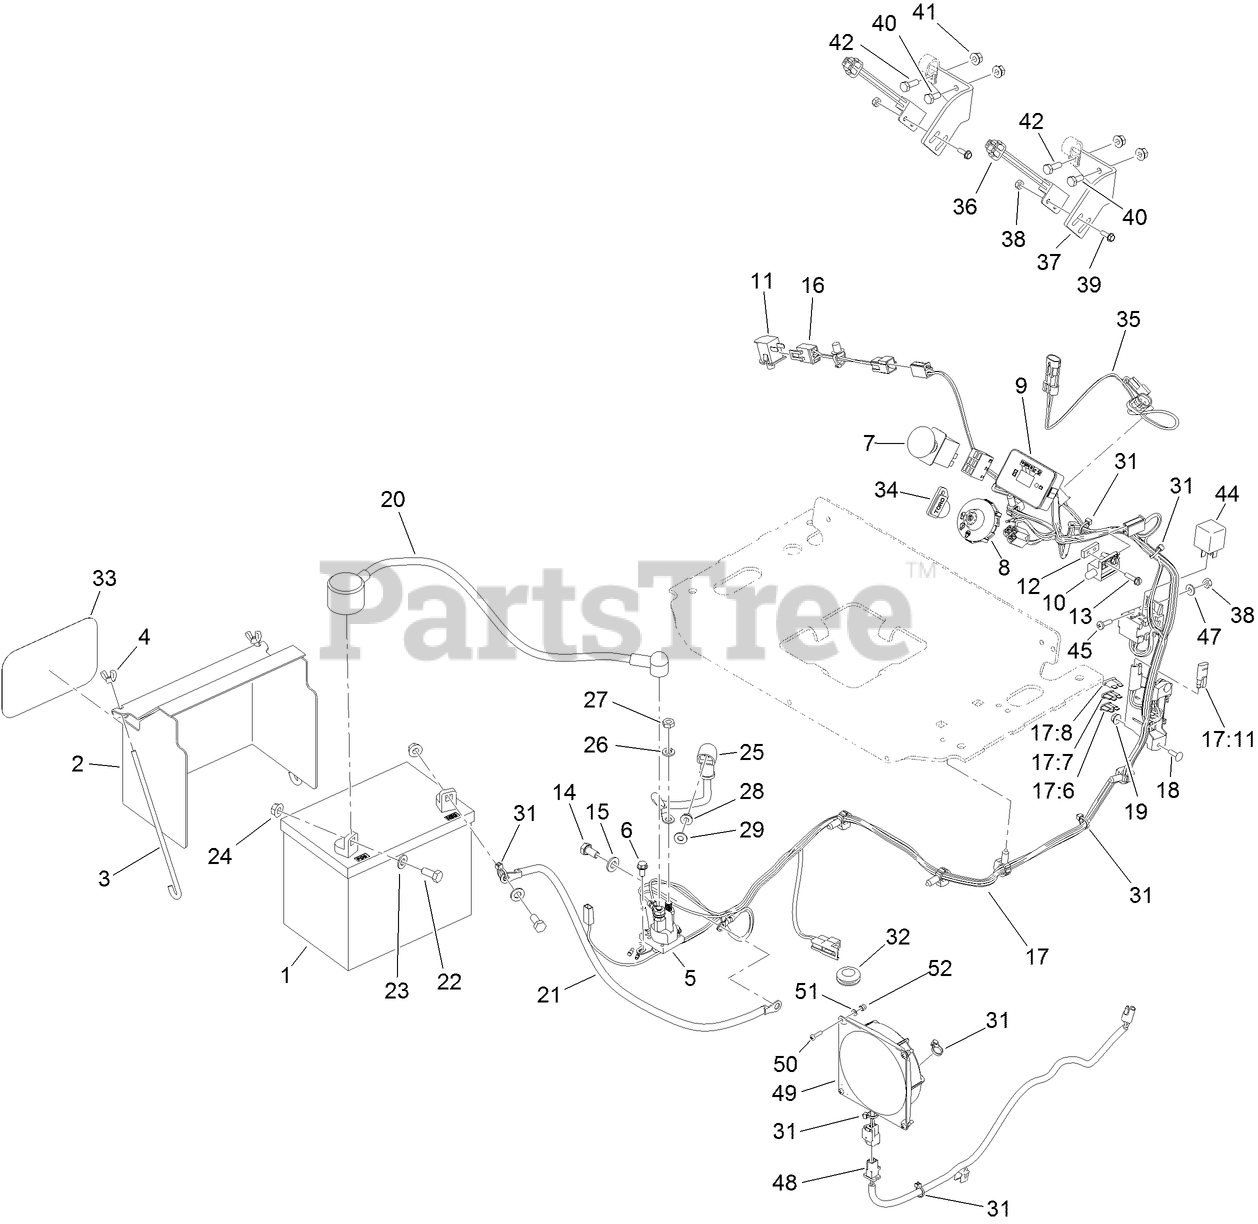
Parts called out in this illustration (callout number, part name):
1	BATTERY-DRY
2	COVER-BATTERY
3	BOLT-HOLDDOWN
4	WINGNUT
5	SOLENOID
6	SCREW-HWH
7	SWITCH-PTO, ON-ON-(ON)
8	SWITCH-IGNITION
9	MODULE-HOUR METER
10	SWITCH-CLOSED, NORMALLY
11	SWITCH-BAIL
12	PLATE-TAPPED
13	SCREW-HWH
14	SCREW-HH
15	WASHER-PLAIN
16	HARNESS-WIRE, JUMPER (OPC)
17	HARNESS-WIRE
17:6	FUSE-BLADE, 30 AMP
17:7	FUSE-BLADE, 25 AMP
17:8	FUSE-BLADE, 10 AMP
17:11	CAP-PLUG
18	BOLT-CARR
19	NUT-HF
20	CABLE-BATTERY, POSITIVE
21	CABLE-BATTERY, BLACK
22	SCREW-HH
23	WASHER-PLAIN
24	NUT-HHF, SMOOTH
25	CABLE-BATTERY, RED
26	WASHER-LOCK
27	NUT-JAM
28	NUT-HF
29	WASHER-FLAT
31	TIE-CABLE
32	GROMMET
33	DECAL
34	KEY-IGNITION
35	HARNESS-WIRE, NEUTRAL SWITCH
36	SWITCH-PROXIMITY
37	BRACKET-MOUNT, SWITCH
38	NUT-LOCK, NI
40	SCREW-HH
41	NUT-HHF
42	SCREW-HH
45	SCREW-PPH
47	WASHER-FLAT
48	HARNESS-WIRE, FAN
49	FAN-ELECTRIC
50	SCREW-PPH
51	WASHER-FLAT
52	NUT-LOCK
